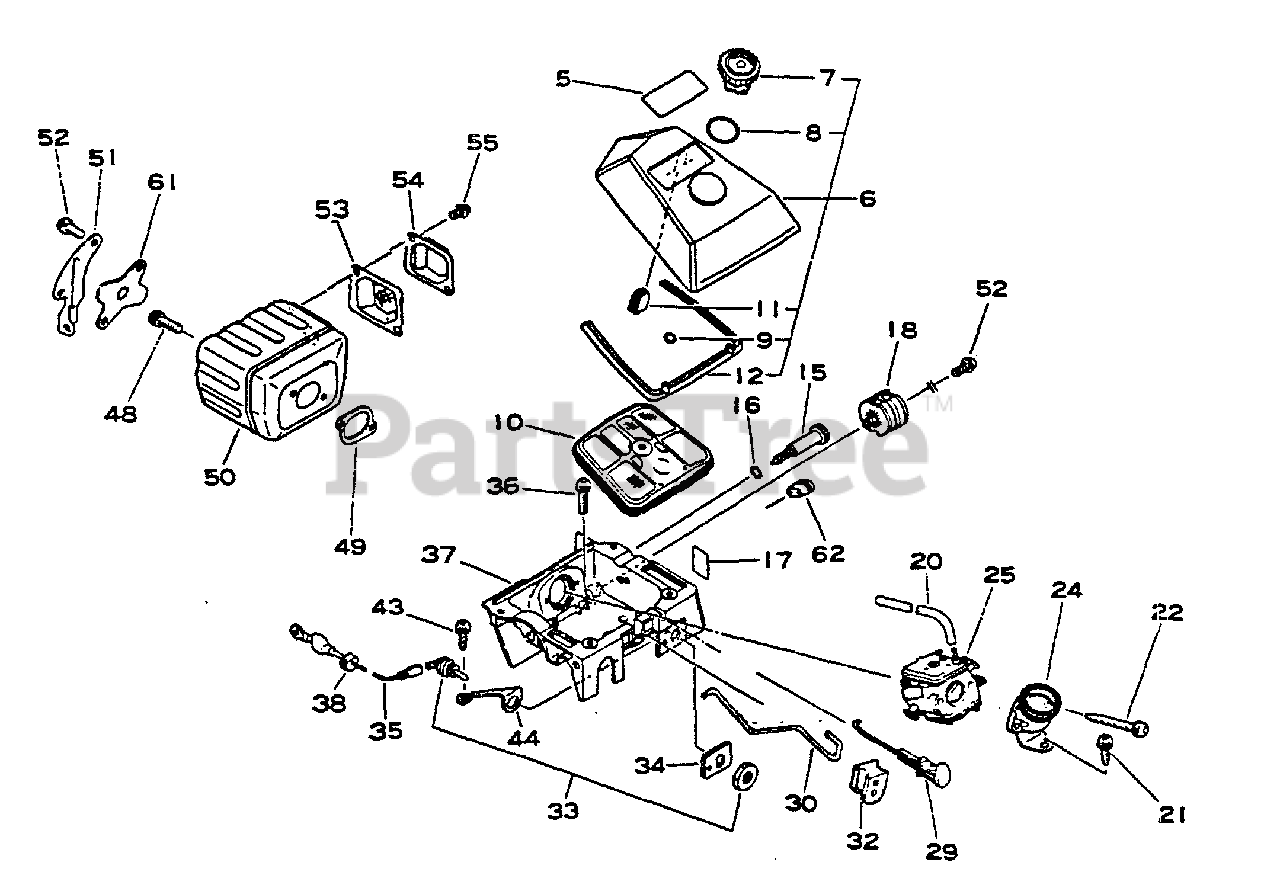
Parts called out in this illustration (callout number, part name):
5	LABEL
6	AIR FILTER COVER ASSY
7	THUMBSCREW
8	O-RING - 22
9	O-RING - 10
10	FILTER, AIR
12	SEAL
15	SCREW, IDLE ADJUST
16	O-RING - 7
17	LABEL - IDLE
18	CUSHION
20	FUEL PIPE KIT
21	SCREW - 5X14
22	SCREW - 5X55
23	PLATE, PREVENT
24	ADAPTOR, INTAKE
25	CARBURETOR
29	ROD, CHOKE
30	ROD, THROTTLE
32	GUIDE, THROTTLE ROD
33	IGNITION SWITCH ASSY
34	LABEL - STOP
35	LEAD - GROUND
36	SCREW - 5X20
37	CASE, CARBURETOR
43	SCREW - 5X20
44	TERMINAL - GROUND
48	SCREW - 5X20
49	GASKET, EXHAUST
50	MUFFLER
51	BRACKET, MUFFLER
52	SCREW - 5X14
53	SCREEN, SPARK ARRESTOR
54	GUIDE, EXHAUST
55	SCREW - 4X10
61	COVER, MUFFLER
